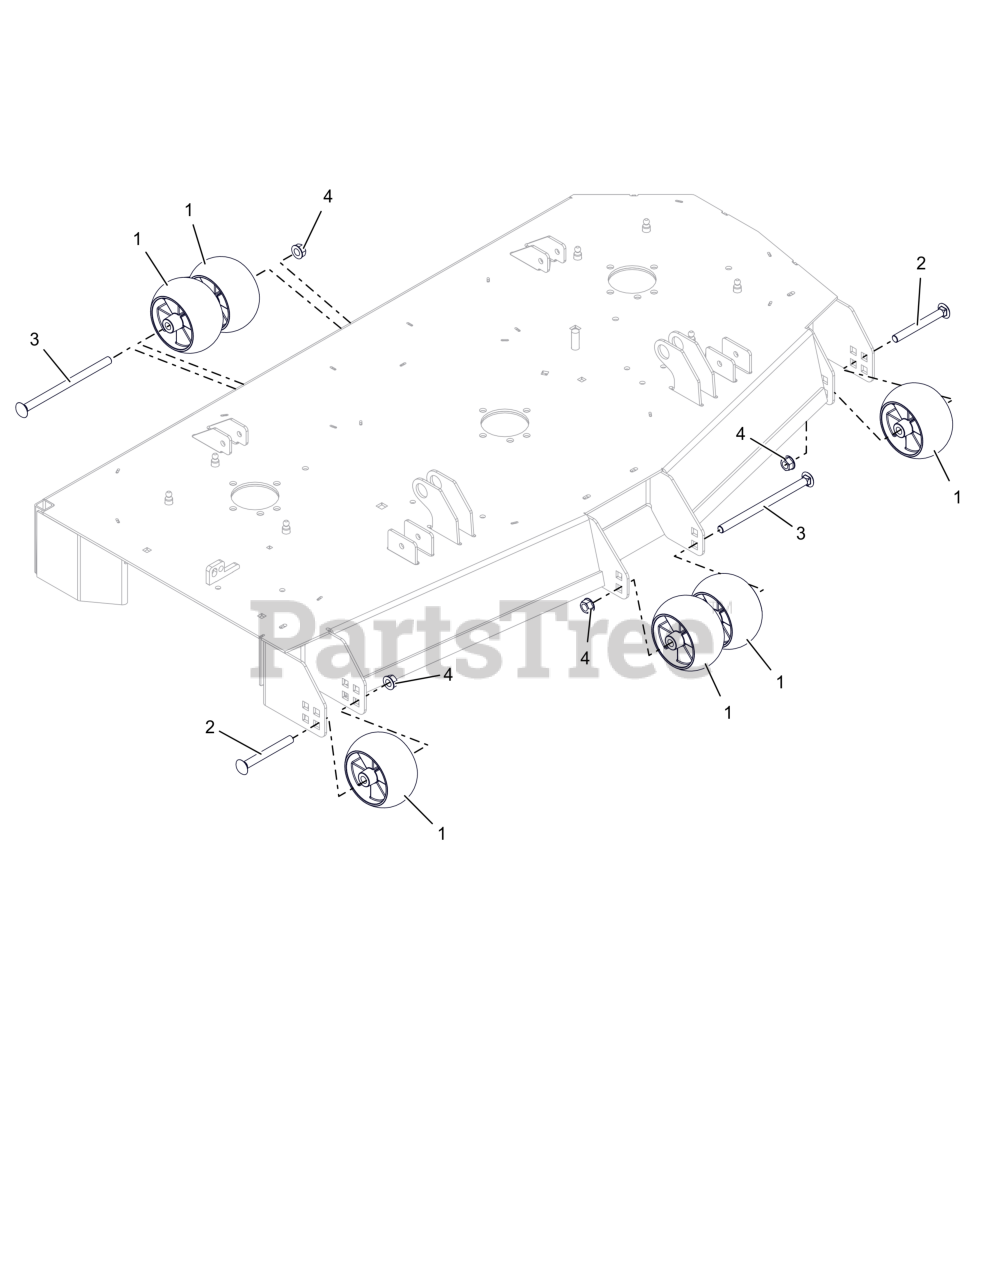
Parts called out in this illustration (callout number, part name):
1	WHEEL, ANTI SCALP - 5X3 CTR W/RIBS
2	BOLT, RHNS .50-13X4.50 G5 ZCC NS
3	BOLT, RHNS .50-13X8.00 G5 ZCC NS
4	NUT-LK-CTR-FLG .500-13 GG ZCC
